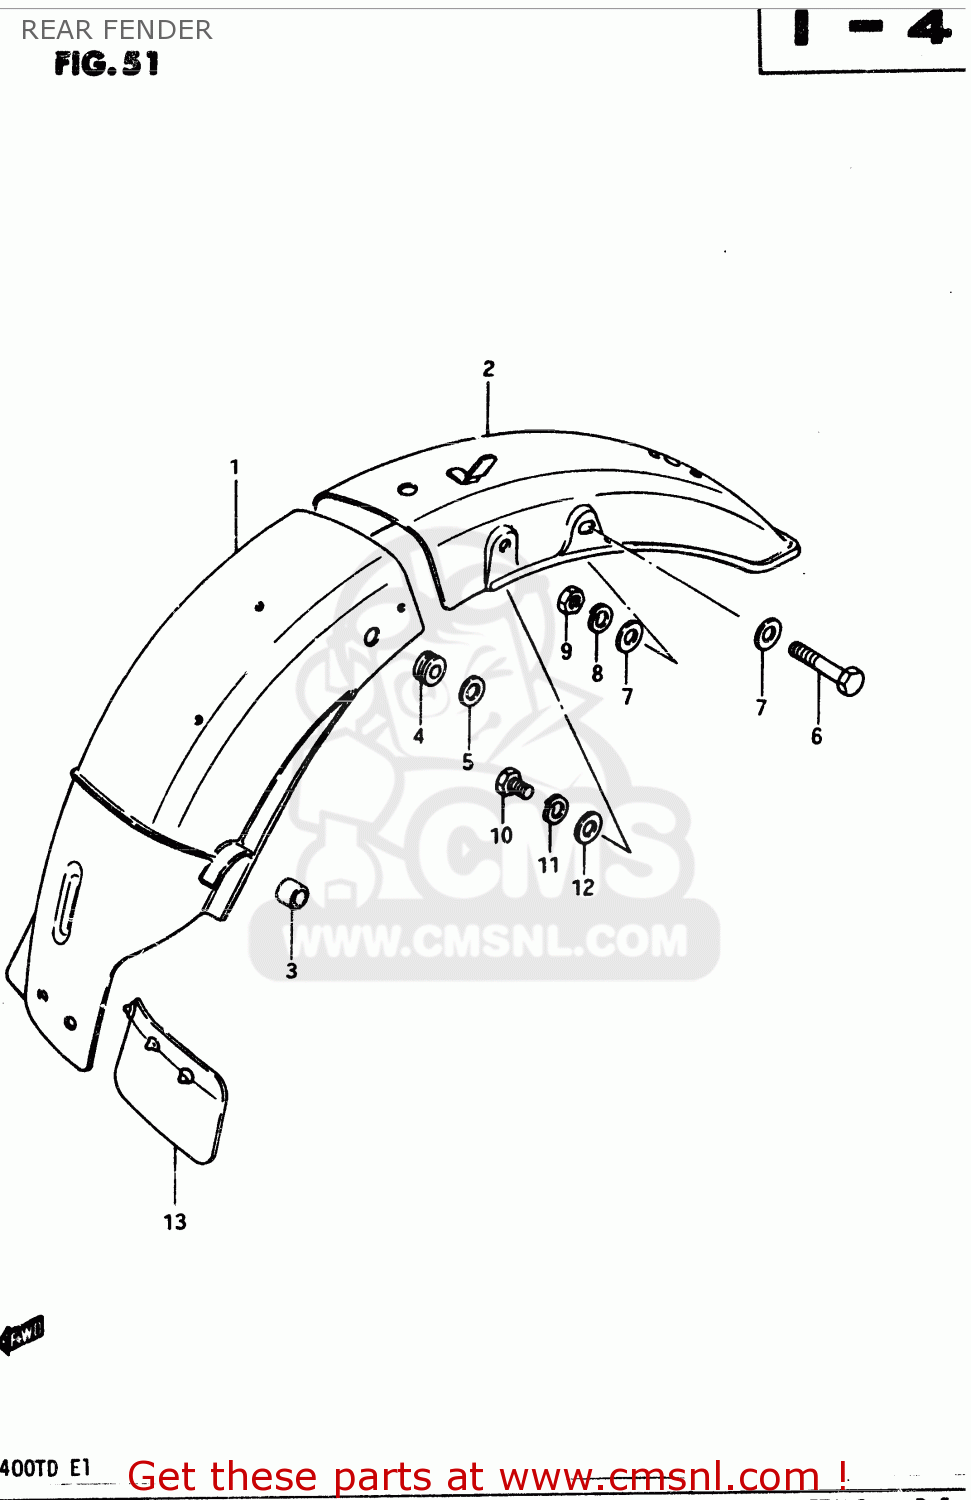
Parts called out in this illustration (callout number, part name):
1	FENDER,REAR
2	BODY, REAR FENDER REAR
3	CUSHION
4	CUSHION
5	WASHER
6	BOLT
7	WASHER
8	LOCK WASHER
9	NUT
10	BOLT 8X12
11	LOCK WASHER
12	WASHER
13	GUIDE,RR FENDER MUD
